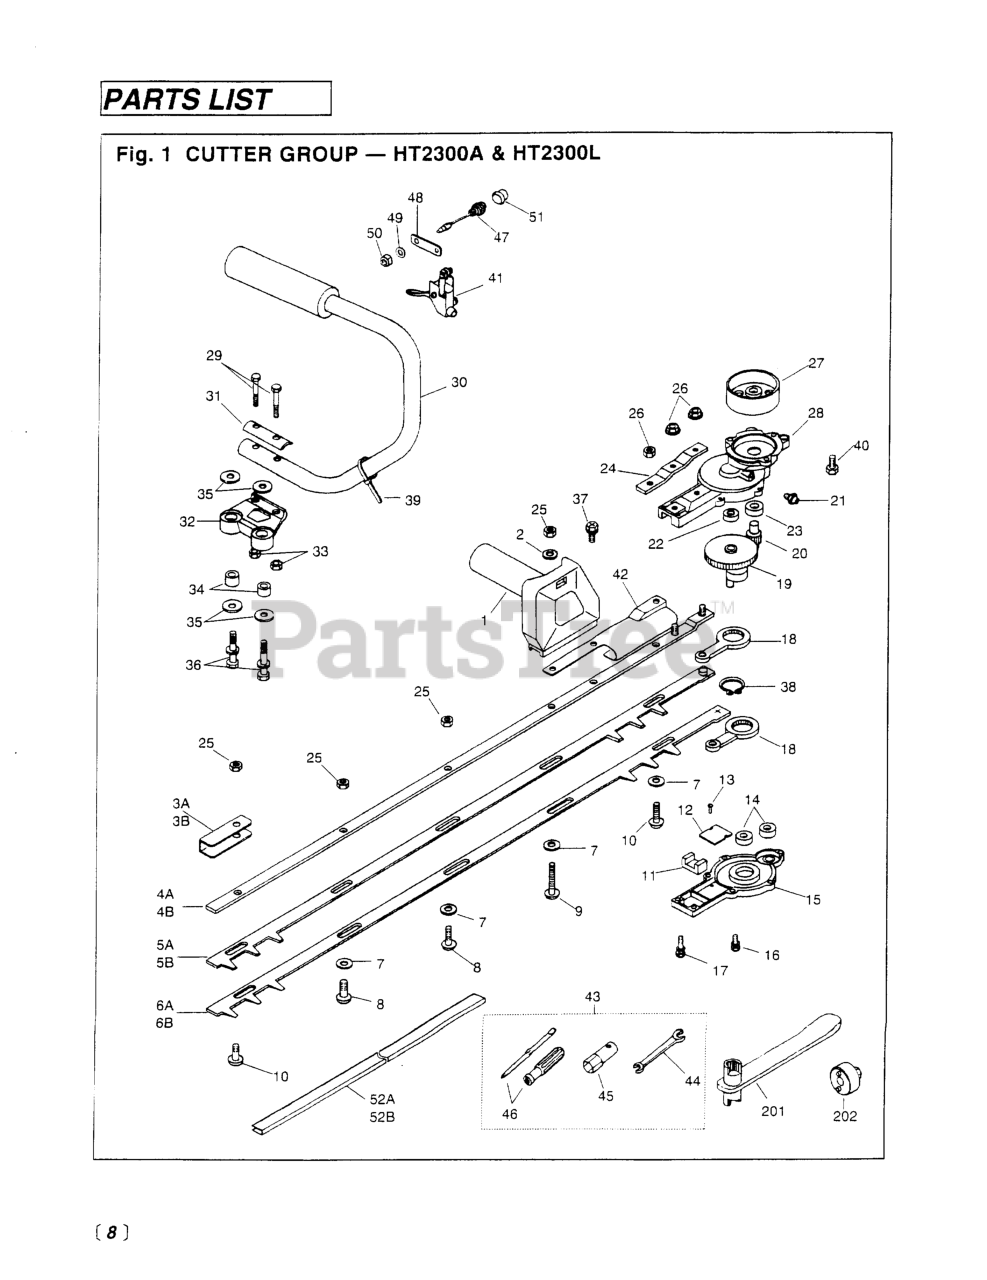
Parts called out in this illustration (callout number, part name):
1	HANDLE (RPLS -12100)
3A	REINFORCE, END
5A	BLADE, UPPER, 30
6A	BLADE, LOWER, 30
7	WASHER (RPLS 3873-11760)
11	FELT
12	PLATE
13	SCREW, M3 x 5
14	BEARING
15	CASE, LOWER
16	BOLT, M5 x 16
17	BOLT, M5 X 20
18	ROD
19	GEAR COMPLETE
20	PINION
21	FITTING, GREASE
22	BEARING
23	BEARING
24	PLATE (RPLS 3880-11130)
25	NUT, M6
26	NUT
27	DRUM, CLUTCH
28	CASE, UPPER (RPLS -11110)
30	HANDLE, LEFT
32	BRACKET
33	NUT (RPLS 3873-14470)
37	BOLT
38	RING, SNAP, M25 X 1.2
39	BAND, CABLE
40	BOLT, M6 X 14
41	LEVER ASSEMBLY
42	PROTECTOR
43	TOOL SET
44	SPANNER, 8 X 10 (RPLS 2540- )
45	SOCKET, HEX, 3/4
46	SCREWDRIVER
48	PLATE
49	WASHER
50	NUT
51	CAP
52A	COVER, BLADE (30
202	WRENCH (TOOL)
